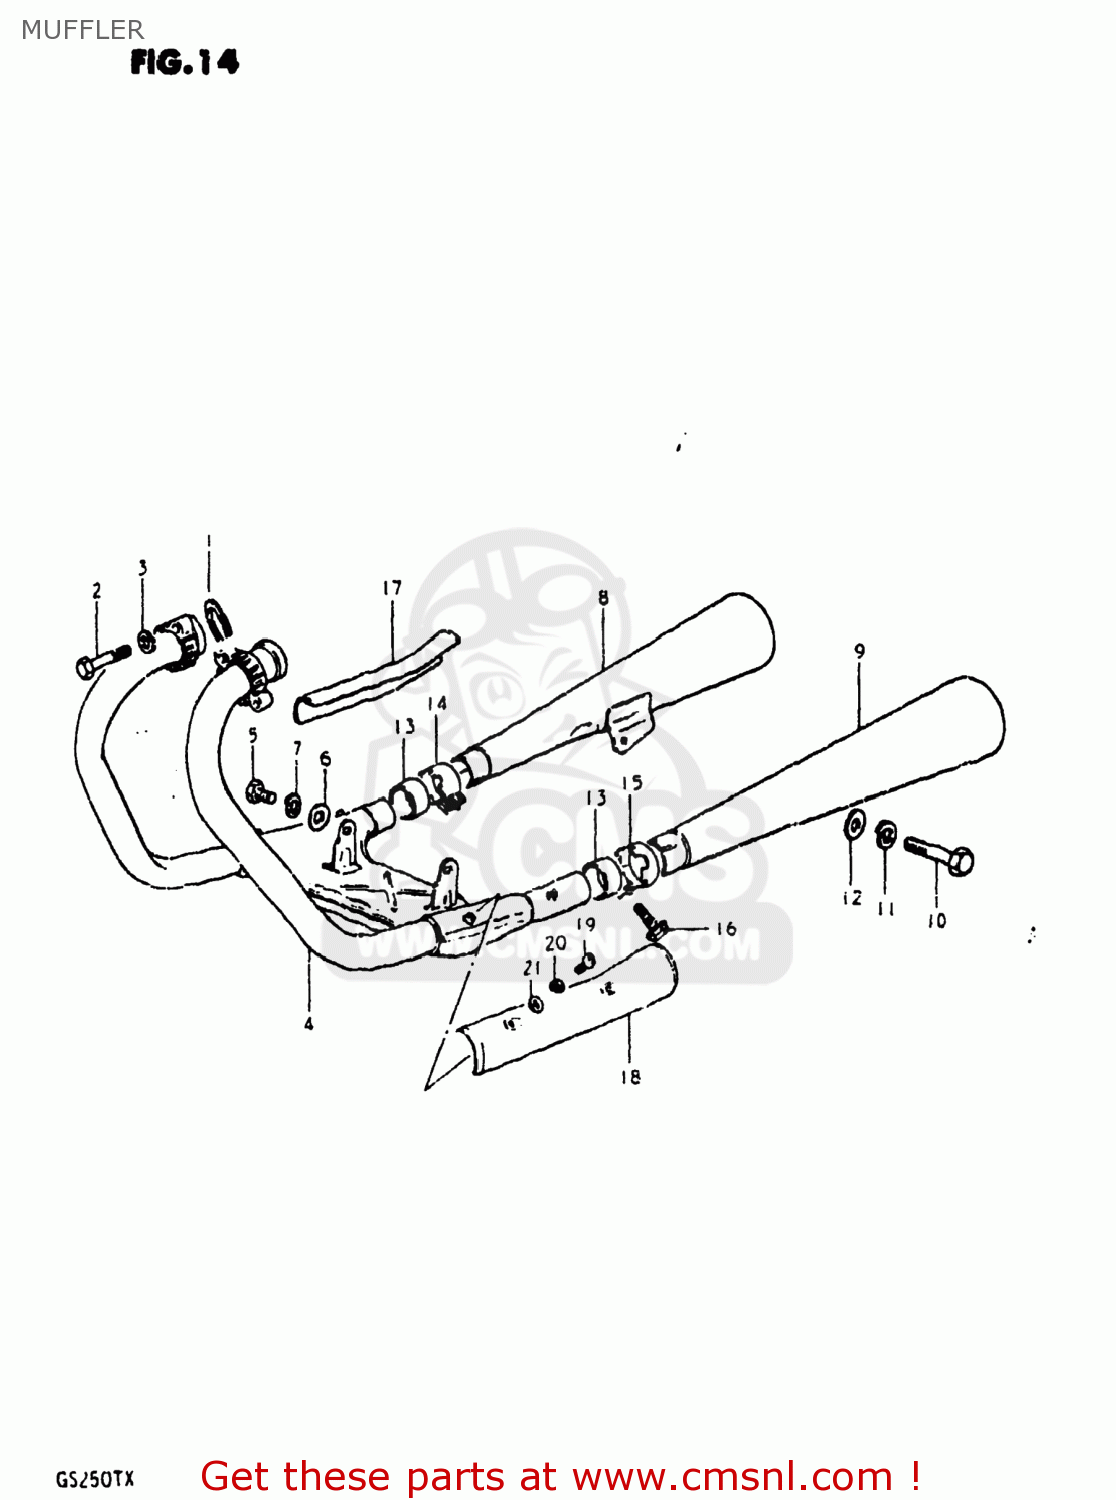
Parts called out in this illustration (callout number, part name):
1	GASKET,EXHAUST PIPE (NAS)
2	BOLT
3	LOCK WASHER
4	PIPE,EXHAUST
5	BOLT
6	LOCK WASHER
7	WASHER
8	BODY,MUFFLER
9	BODY,MUFFLER
10	BOLT 10X30
11	LOCK WASHER
12	WASHER
13	CONNECTOR,MUFFLER
14	CLAMP,MUFFLER CONNECTOR,R
15	CLAMP,MUFFLER CONNECTOR,L
16	BOLT
17	COVER,MUFFLER
18	COVER,MUFFLER,LEFT
19	SCREW
20	LOCK WASHER
21	WASHER
